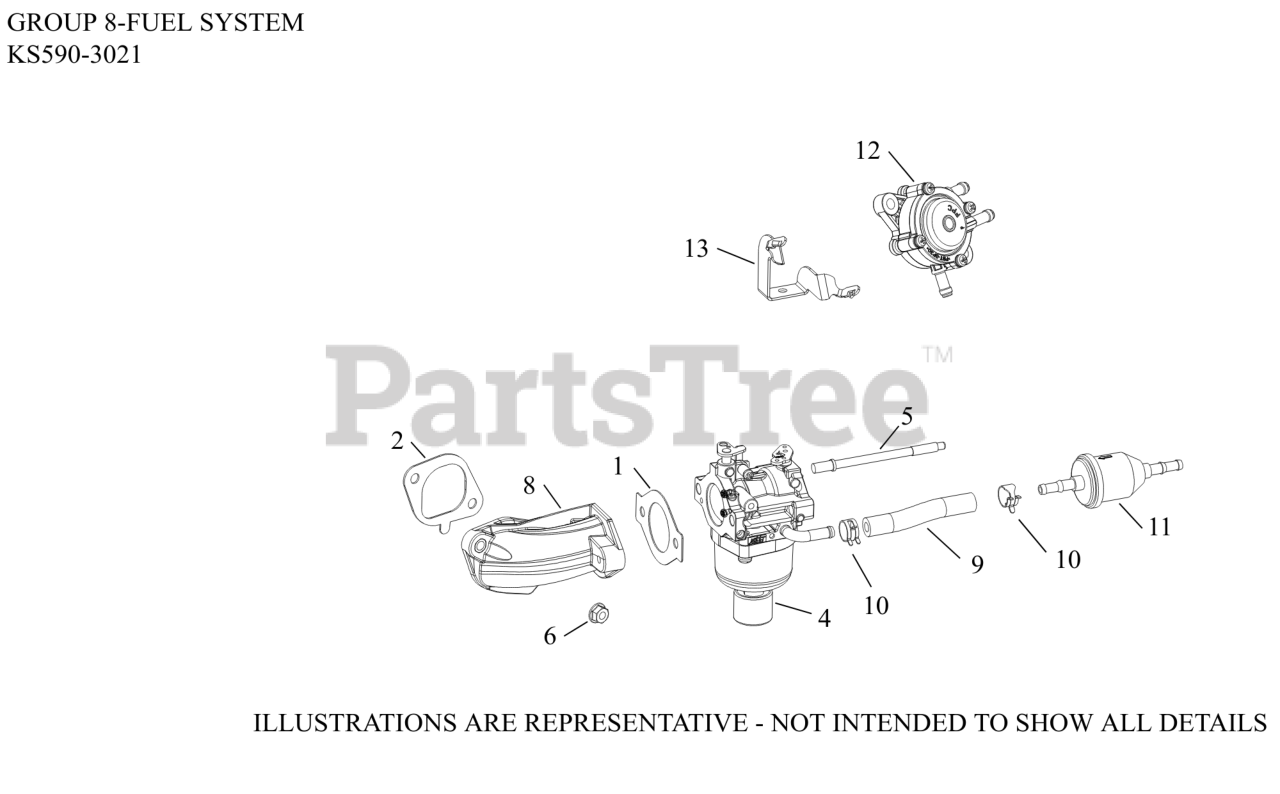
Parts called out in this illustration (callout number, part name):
1	GASKET, CARBURETOR (THROTTLE)
2	GASKET, INTAKE MANIFOLD
4	KIT,CARB(NIKKI)
5	STUD, CARBURETOR
6	NUT, FLG M6X1.0
8	MANIFOLD, INTAKE ASSEMBLY
9	HOSE,LW PERM.FUEL 24.00"-USE 25 111 81-S
10	SPRING CLAMP, HOSE
11	FILTER,FUEL 51 MICRON (FUEL PUMP)
12	PUMP, FUEL (PULSE)-(#2539326S)
13	BRACKET, FUEL PUMP
NI	HIGH ALTITUDE KIT (5000 FT)
NI	KIT, OVERHAUL
NI	KIT, CHOKE SHAFT
NI	KIT, O-RING
NI	KIT, SOLENOID (NIKKI)
NI	KIT, BOWL WITH O-RINGS
NI	KIT, FLOAT & INLET NEEDLE FOR FUEL PUMP
NI	KIT, THROTTLE SHAFT
